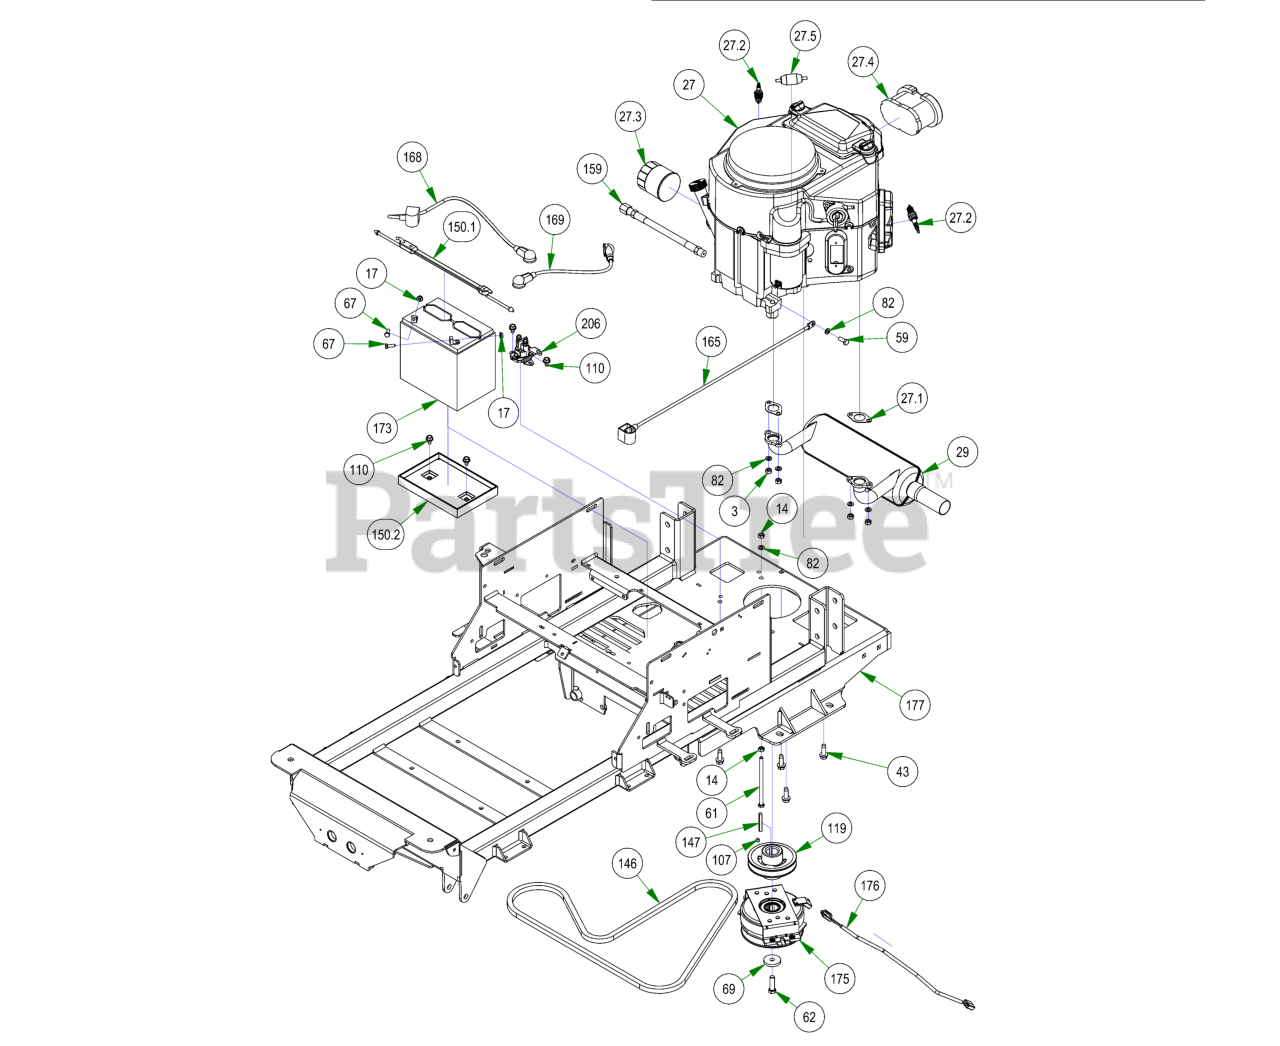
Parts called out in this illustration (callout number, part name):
3	M8-1.25 DIN 934 HEX NUT (CL.8) ZINC
14	5/16-18 HEX NUT ZINC
17	1/4-20 HEX SERRATED FLANGE NUT HARD/ZINC
27	FS730V Engine
27.1	Exhaust Gasket
27.2	Spark Plug - Kawasaki
27.3	22-26 Kaw Oil Filter FR Engine
27.4	Kawasaki Air Filter
27.5	Universal Inline Fuel Filter
29	Kawasaki Muffler 1251
43	3/8-16 X 1-1/8HEX WASHER UNSLOT SERRATED (TRI-LOB) TRS
59	M8-1.25 X 20MM DIN 933 HEX TAP BOLT (CL 8.8) ZINC
61	5/16-18 X 5-1/2 HEX CAP SCREW (GR.5) ZINC
62	7/16-20 X 1-1/2 HEX CAP SCREW (GR.8) w/ Patch
67	1/4-20 X 3/4 HEX CAP SCREW (GR.5) ZINC
69	CLUTCH WASHER
82	5/16 SPLIT LOCKWASHER ZINC
107	5/16-24 X 1/4 SOCKET SET SCREW (CUP PT) PLAIN
110	5/16-18 X 1/2 HWH unslot (F) tcs zinc
119	4 3/4 Motor Pulley
146	75.8" Pump Belt
147	1/4 X 2 SQ MACHINERY KEY 1018 STL PLAIN
150	2023 Battery Hold Down Assembly Strap
150.1	2023 Rubber Battery Hold Down Strap
150.2	Battery Tray
159	Oil drain Hose
165	24 inch Black Cable – MZ/ZT
168	24" Red Battery Cable
169	12" Red Battery Cable
173	SP-35 Battery
176	Clutch Pigtail
177	2023 Maverick Frame - Painted
